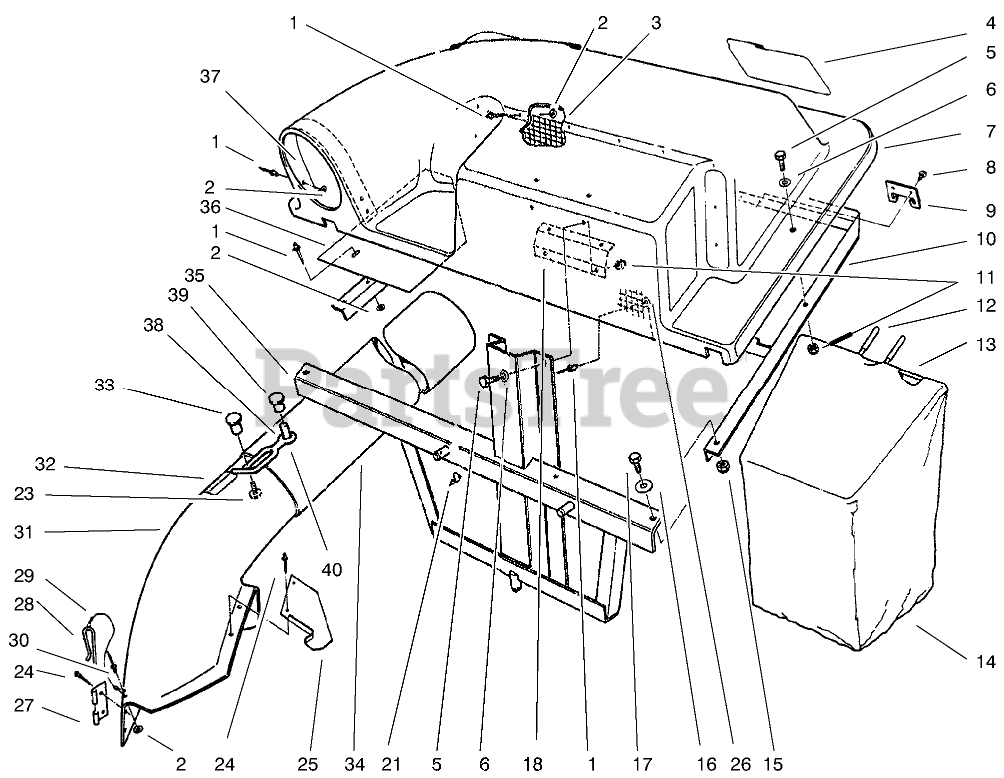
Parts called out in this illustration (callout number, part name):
1	RIVET-POP
2	WASHER-PLAIN
3	SCREEN
4	DECAL-BAGGER, TWIN
5	SCREW-HH
6	WASHER-PLAIN
7	COVER-BAGGER, TWIN
8	SCREW-HWH
9	BRACKET-FRAME, BAG
10	Cover-Frame
11	NUT-LOCK, NI
12	GRIP-HANDLE, BAG
13	Frame-Bag
15	NUT-LOCK, NI
16	WASHER-FLAT
17	SCREW-HH
18	Plate-Backup
21	PIN-HAIR
23	SCREW-HWH
24	RIVET-BLIND
25	CHUTE SUPT BRKT
27	BRACKET-MOUNTING, CHUTE
28	PIN-LOCKING, CHUTE
29	LANYARD
30	RIVET-BLIND
31	Assembly-Chute (Incl. Ref. #23-30 & 32-33)
32	DECAL-DANGER
34	GRASS DISCHARGE TUBE
35	Frame-Mounting
36	Baffle
37	Support Inlet
38	SPACER-INTERLOCK
39	FASTENER-PANEL
40	RETAINER-DUCT
